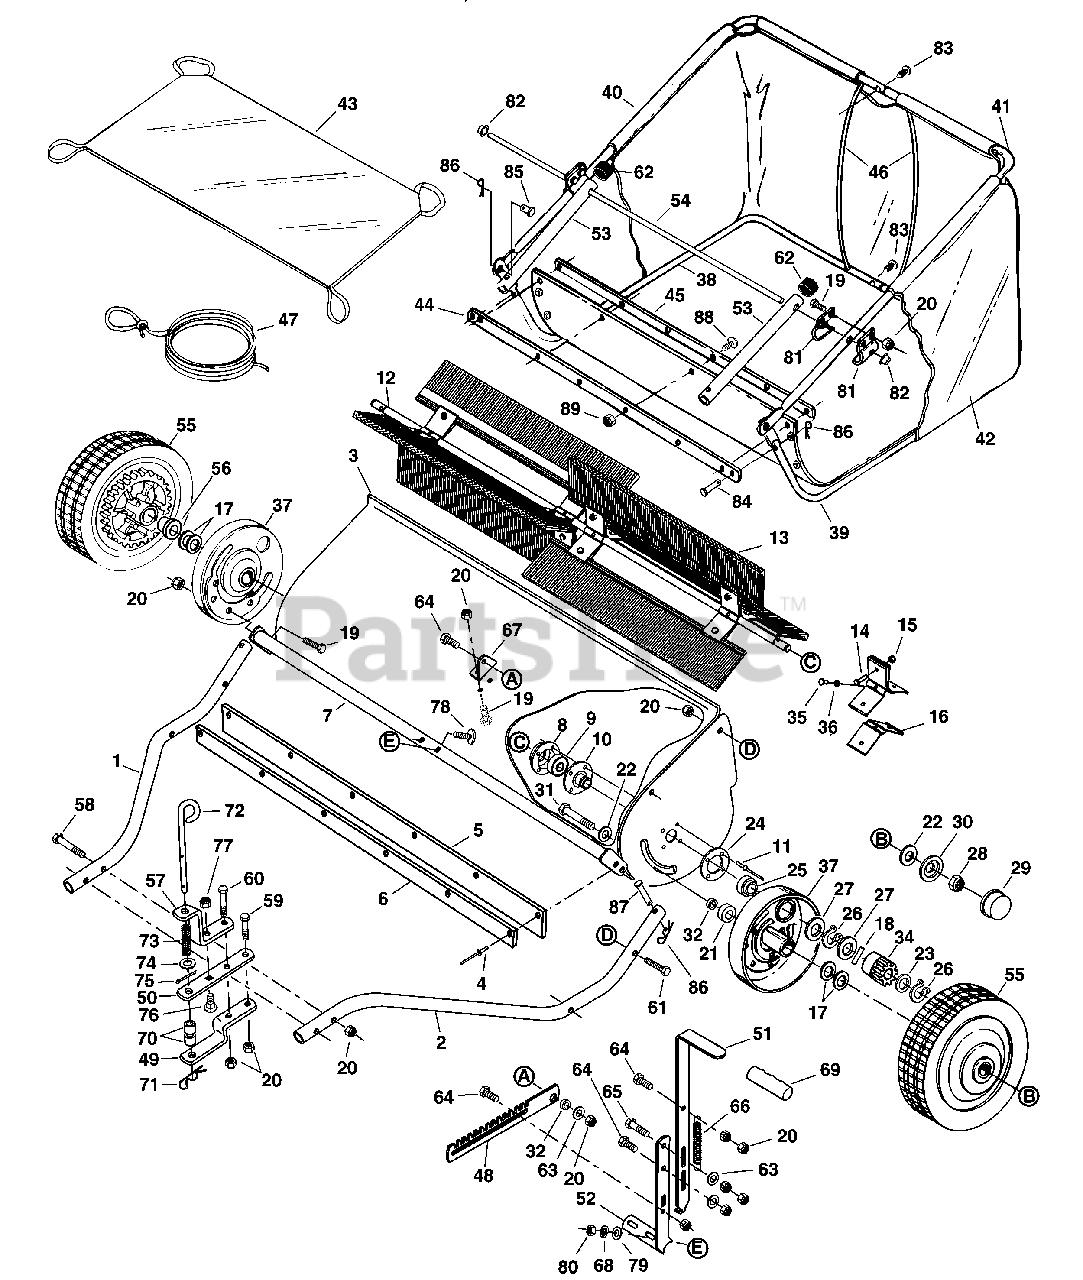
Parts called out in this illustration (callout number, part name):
1	Hitch Tube, R.H.
2	Hitch Tube, L.H.
3	Housing Assembly
5	Skirt, 42"
6	Retainer, Skirt
7	Height Adjustment Tube Ass'y.
8	Retainer, Dust Cover
9	Ball Bearing
10	Brush Bushing Ass'y.
12	Brush Shaft
13	Brush, 42"
14	Bolt, Hex 1/4-20 x 1" Lg.
15	Nut, Nylock 1/4-20 Thread
16	Brush Retainer
17	Washer, Flat .78" x 1.25" x .06"
18	Dowel Pin
19	Bolt, Hex 5/16-18 x 3/4" Lg.
20	Nut, Nylock 5/16-18 Thread
21	Spacer, .41" x 1.125" x .50"
22	Washer, Flat 1-1/2" x .375" x .062"
23	Washer, .849" x .598" x .025"
24	Washer, Special
25	Spacer, .78" x 1.25" x .50"
26	Ring, Retaining .594"
27	Washer, Shim 1-1/8" x .594" x .025"
28	Nut, Nylock 3/8-24 Thread
29	Hub Cap
30	Washer, Hub Cap
31	Bolt, Hex 3/8-24 x 3-1/4" Lg.
32	Spacer, Small
34	Gear, Pinion L.H.
35	Bolt, Hex 1/4-20 x 5/8"
36	Lock Washer, 1/4"
37	Dust Cover Assembly
38	Lower Hopper Tube, R.H.
39	Lower Hopper Tube, L.H.
40	Upper Hopper Tube, R.H.
41	Upper Hopper Tube, L.H.
42	Hopper Bag
43	Wind Screen
44	Strap, Bag Frame
45	Retainer, Bag
46	Rod, Hopper Support 34"
47	Hopper Rope
48	Strap, Height Adjustment
49	Bracket, Hitch
50	Bracket, Hitch
51	Handle, Upper Height Adjustment
52	Handle, Lower Height Adjustment
53	Tube, Bag Arm
54	Rod, Hopper Bag Pivot
55	Wheel & Tire Ass'y.
56	Wheel Bearing
57	Bracket, Hitch Pin
58	Bolt, Hex 5/16-18 x 3" Lg.
59	Bolt, Hex 5/16-18 x 2-1/4" Lg.
60	Bolt, Hex 5/16-18 x 2-1/2"
61	Bolt, Hex 5/16-18 x 1-3/4" Lg.
62	Cap, Vinyl
63	Washer, Flat 5/16"
64	Bolt, Hex 5/16-18 x 1"
65	Bolt, Hex 5/16-18 x 1-1/4"
66	Spring, Extension
67	Angle Bracket
68	Lock Washer, 5/16"
69	Grip, Height Adjust
70	Spacer, Hitch
71	Hairpin Cotter, 1/8"
72	Pin, Hitch
73	Spring, Hitch Pin
74	Washer, 7/16" Flat
75	Pin, Cotter 1/8" x 3/4" Lg
76	Bolt, Carriage 3/8-16 x 1"
77	Nut, Nylock 3/8-16
78	Bolt, Cvd. Hd. 5/16-18 x 1-5/8" Lg.
79	Washer, Bowed 1" x .32" x .06"
80	Nut, Hex 5/16-18 Thread
81	Hopper Mount Clamp
82	Palnut, 3/8"
83	Plug, 1/4"
84	Pin, Clevis 1/4" x 1-1/8"
85	Pin, Clevis 3/8" x 1/2"
86	Hairpin Cotter, 3/32" #3
87	Pin, Clevis 1/4" x 1-1/2" Lg.
88	Screw, #10-32 x 5/8" Truss Head
89	Nut, Nylock #10-32
